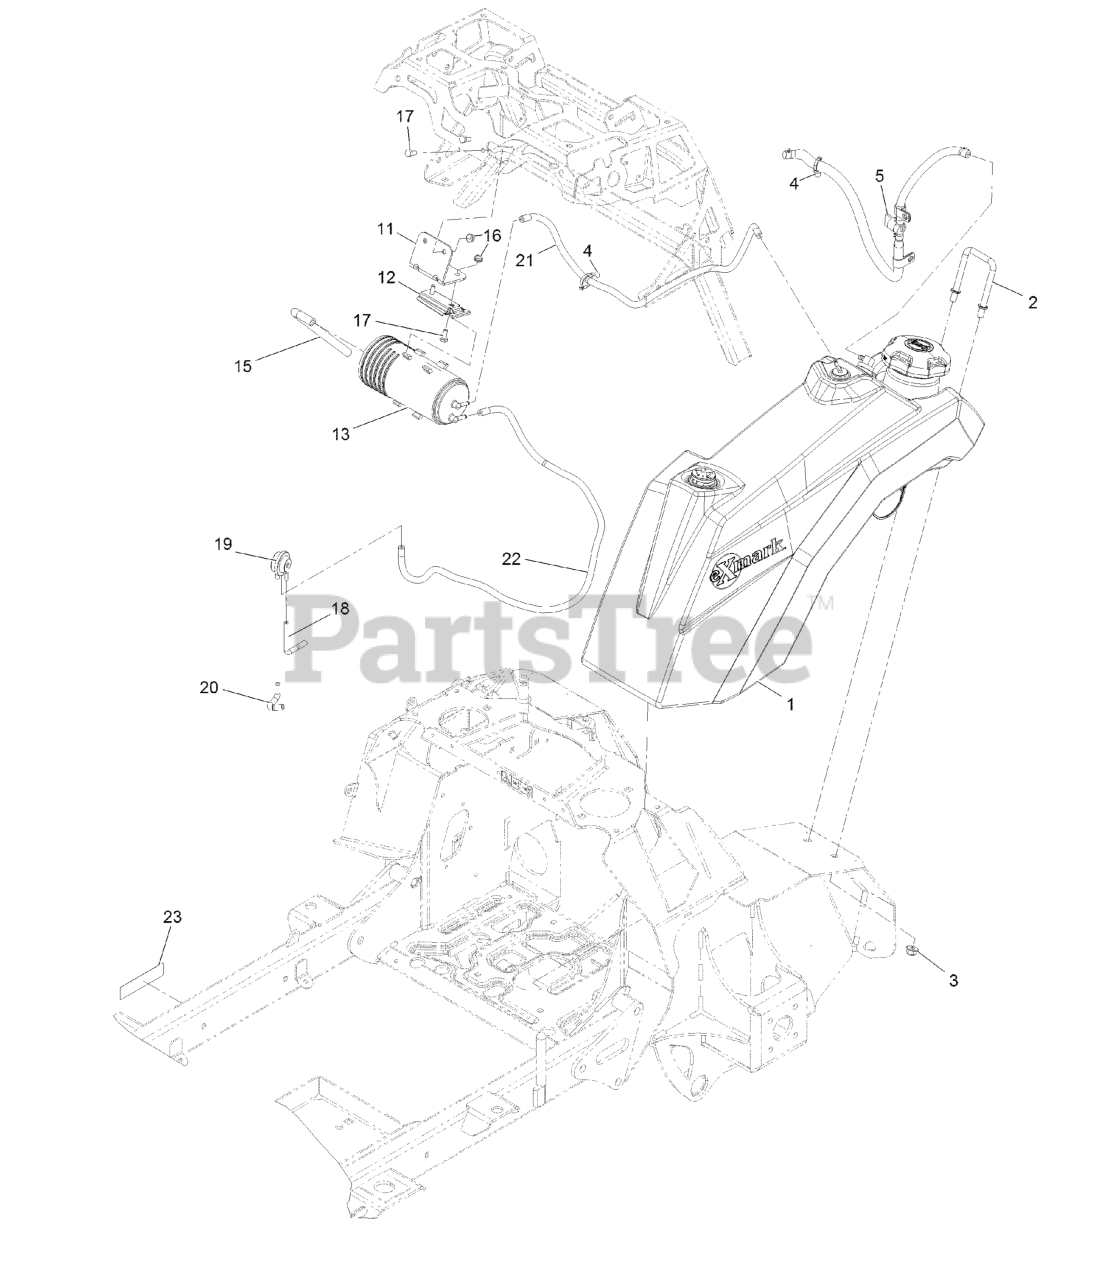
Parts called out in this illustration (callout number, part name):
1	ASSEMBLY, FUEL TANK
2	CLAMP, TANK
3	NUT-HF, NI
4	CLIP-TIE
5	ASM-FUEL LINE & VALVE
11	Bracket-Carbon Canister
12	BRACKET-CANISTER, CARBON
13	CANISTER-CARBON, 800CC
15	HOSE-VENT, CANISTER
17	SCREW-HH
18	HOSE-VENT, FORMED
19	VALVE-CONTROL, VACUUM
20	HOSE-VENT, FORMED
21	HOSE-FUEL
22	HOSE-FUEL
23	DECAL-ARRESTOR, SPARK
